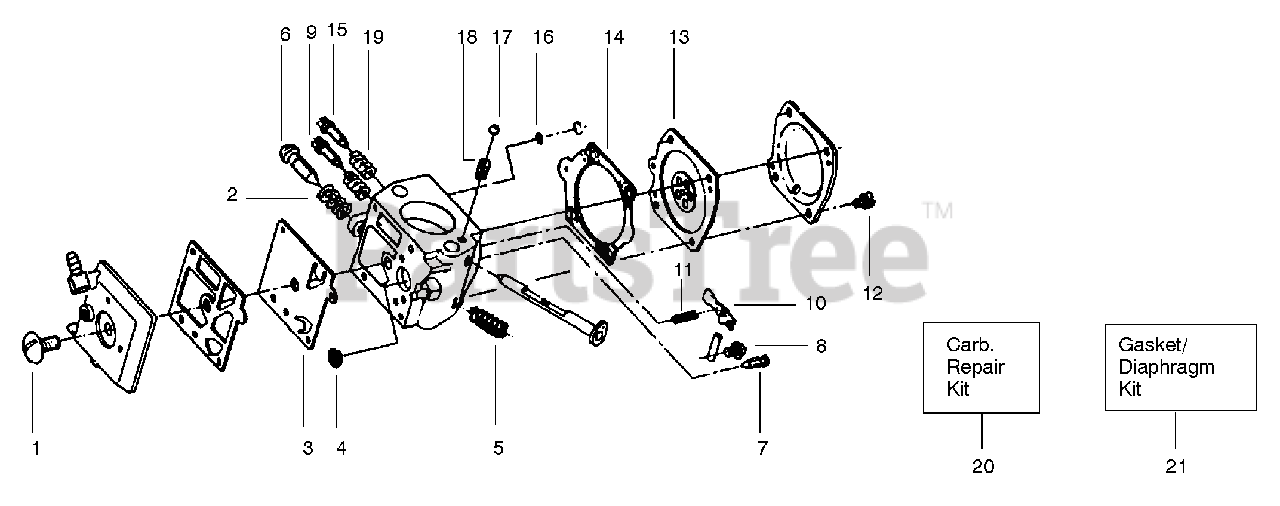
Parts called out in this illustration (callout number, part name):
2	Idle Adjust Spring
3	Pump Diaphragm
4	Inlet Screen
5	Throttle Spring
6	Idle Adjust Screw
7	Inlet Needle Valve
9	Idle Needle
10	Metering Lever
13	Metering Diaphragm Assy
14	Metering Diaphragm Gasket
15	High Speed Needle
16	Check Valve Screen
18	Spring-Choke
19	Needle Adjusting Spring
20	Carb Repair Kit
21	Gasket/Diaphragm Kit
